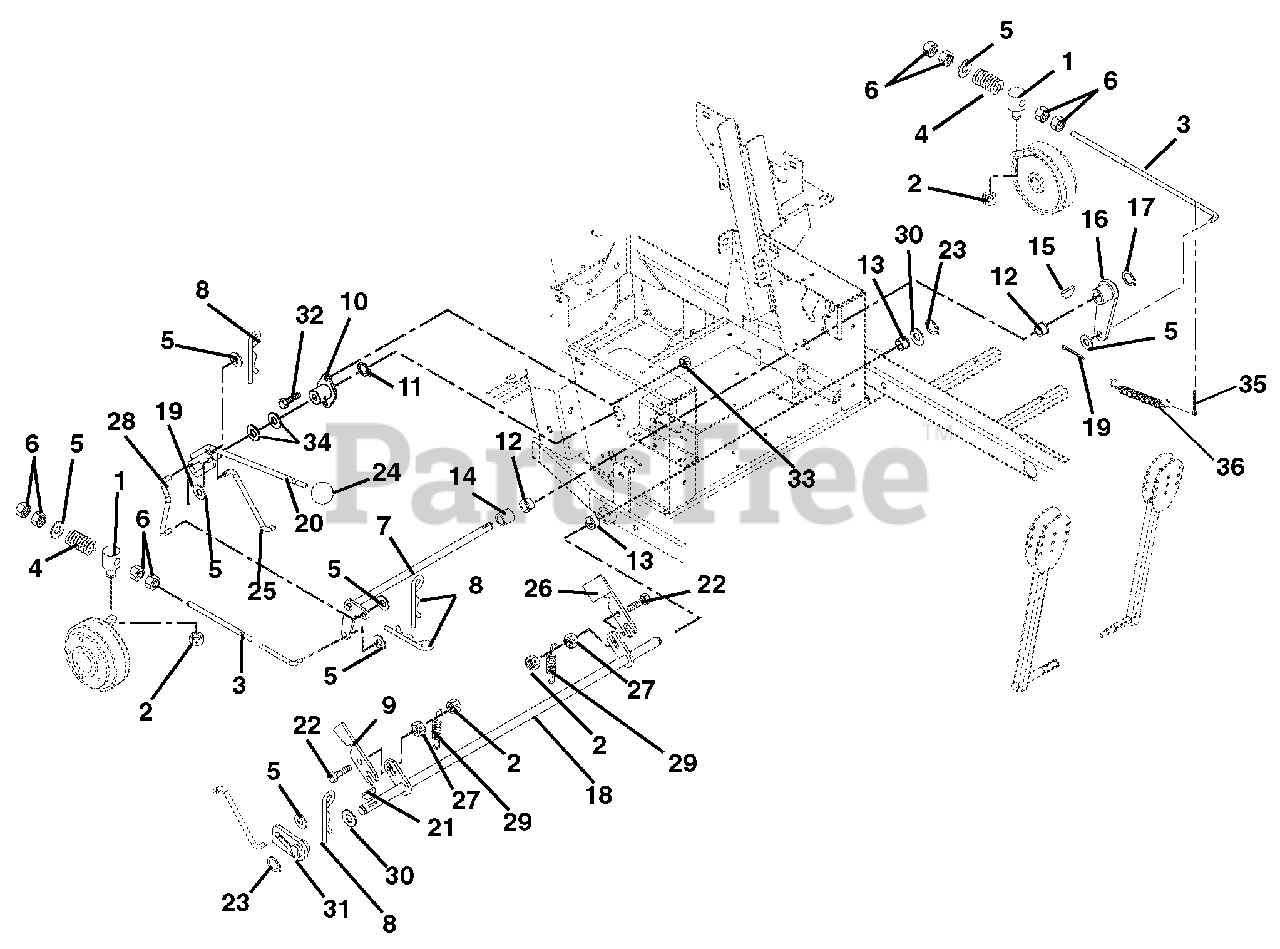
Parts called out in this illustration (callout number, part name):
1	Pivot, Brake Rod
2	Nut, Locking Center .31-18
3	PTO Link Rod
4	Spring, Compression .142 x .710 x 1.75
5	Washer, Flat Steel .406 x .812 x .065
6	Nut, Hex .38-16
7	Shaft, Brake Cross
8	Pin, Hair
9	Slide, Interlocking Brake
10	Bushing, Flange
11	Ring, Retaining External .625 x .05
12	Bushing, Flange Nylon .762 x 1.00 x .58 x 1.48
13	Bushing, Flange .515 x .75 x .745 x 1.00
14	Bushing, Sleeve .75 x 1.00 x .75
15	Key, Woodruff .19 x .75 Hard #9
16	Arm, Brake
17	Ring, Retaining External .69 x .077
18	Weldment, Mechanical Brake
19	Pin, Cotter External .09 x .75
20	Weldment, Handle
21	Key, Woodruff .13 x .63
22	Bolt, Round Head Square Neck .31-18 x 1.25 Grade 5
23	Ring, Retaining External .50 x .05
24	Grip, Handle
25	Linkage, Brake Actuating
26	Interlock, Safety Switch
27	Nut, Locking Top Flange .31-18
28	Linkage, Brake Actuating
29	Spring, Tension .048 x .44 x 1.75
30	Washer, Flat Steel .505 x 1.00 x .062
31	Weldment, Parking Brake Hub
32	Bolt, Hex .31-18 x .75 Grade 5
33	Nut, Locking Top Flange .31-18
34	Washer, Flat Steel .630 x 1.25 x .062
35	Pin, Cotter .12 x .75 Extended Prong Square Cut
36	Spring, Extension
